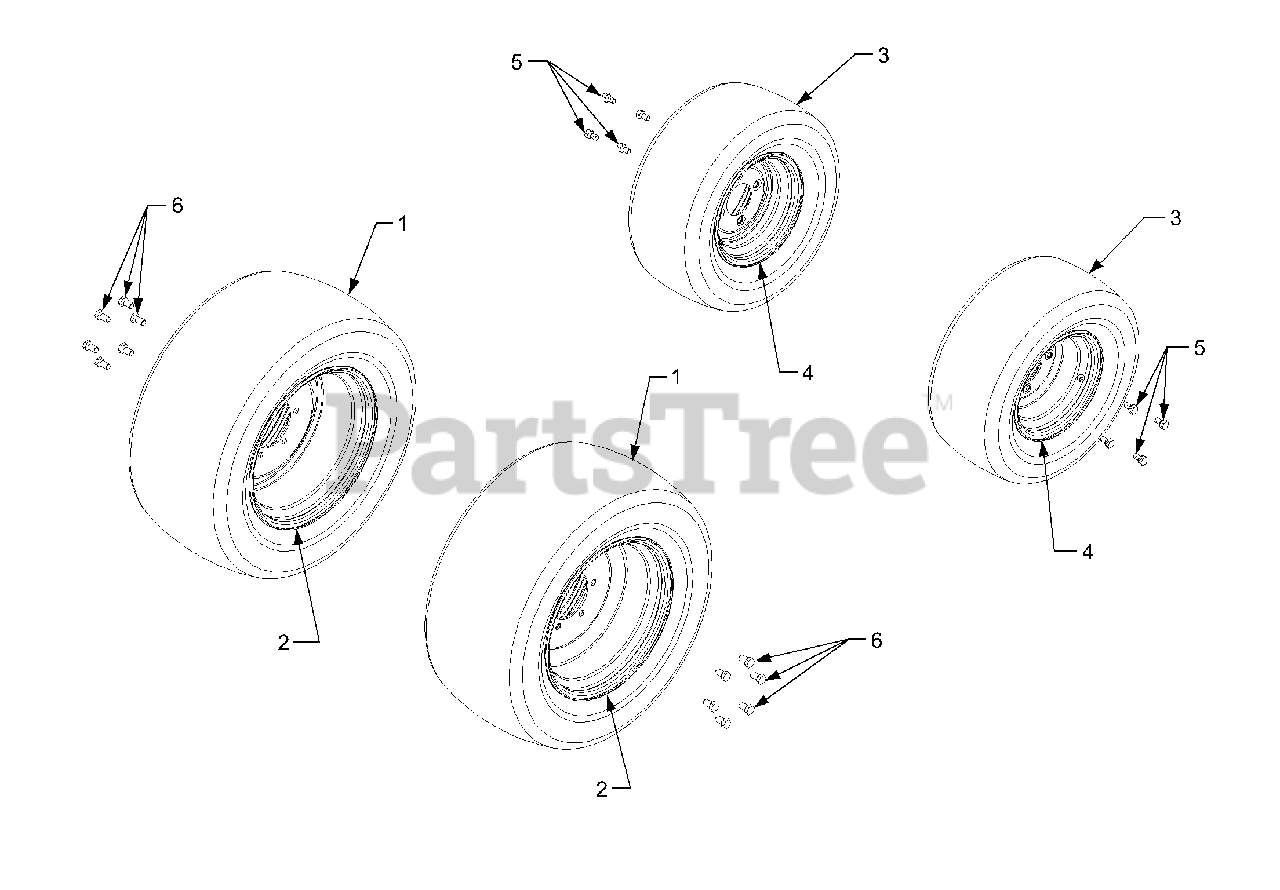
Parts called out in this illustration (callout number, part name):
1	Tire, Turf, 27 x 12.0 x 15
2	Rim Assembly
3	Tire, Tuft, 20 x 9 x 8
5	Screw, Lug, M12
6	Bolt, Lug, M14 x 1.5 x 20
